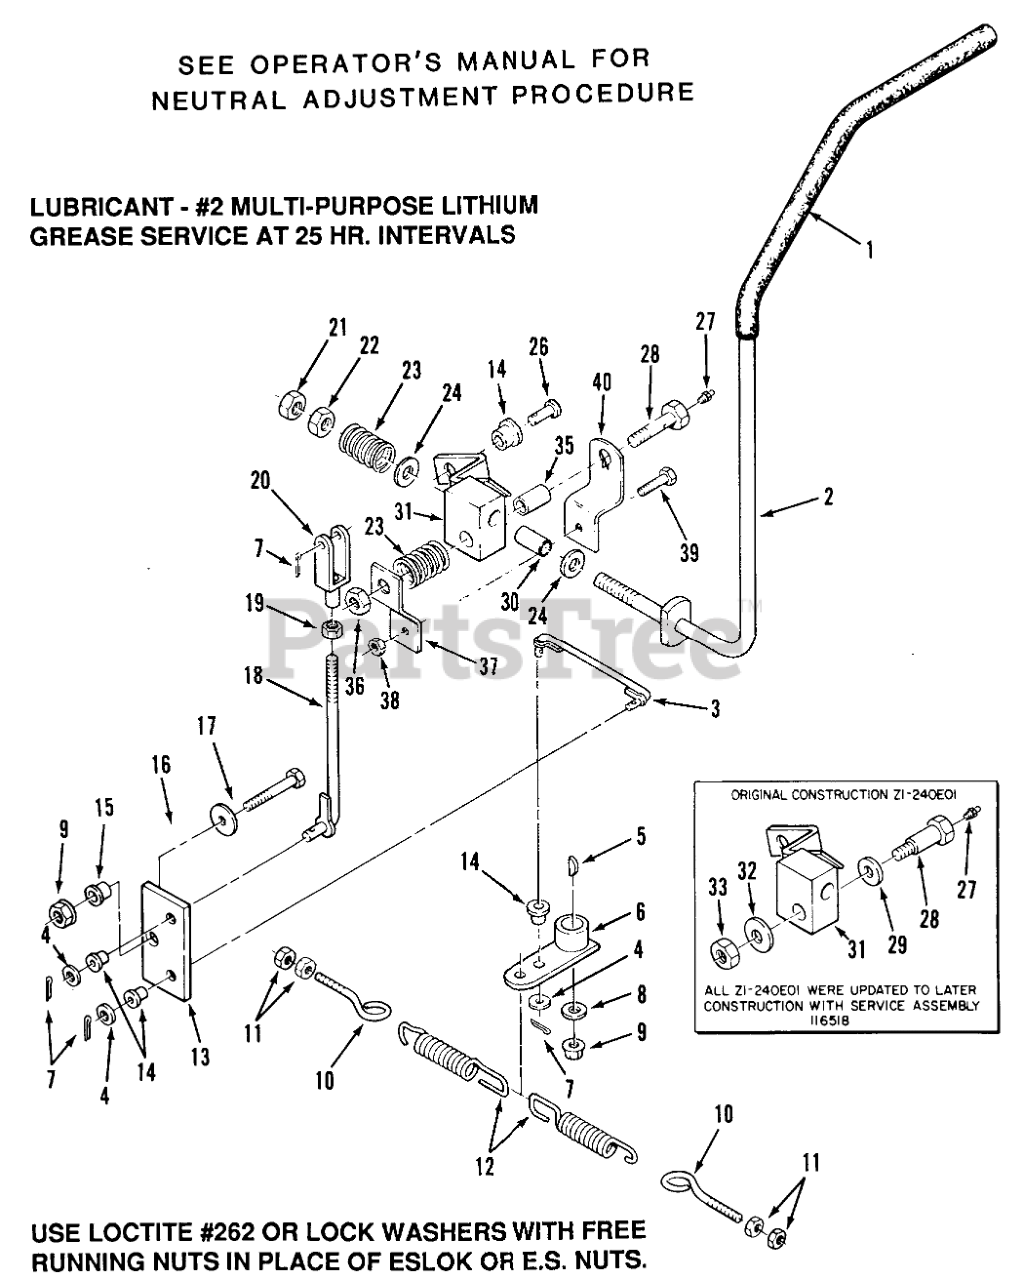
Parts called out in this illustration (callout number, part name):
1	Grip
2	ASSY-STEERING LVR LH
3	Lower Drive Linkage RH
4	WASHER 5/16 SAE
5	KEY WOODR 1/8X1/2 DI
6	Arm-Hydro Control
8	Washer
9	NUT
10	EYE BOLT 1/4-20
11	Nut
12	SPG-NEUTRAL 20217-35
13	Pivot Block
14	BUSHING-FLANGED
15	SPACER-LIFT LINK
16	WASHER
17	BOLT
18	ASS'Y-ROD
19	Nut-Lock
20	CLEVIS
21	Jam Nut
22	Eslok Nut
23	SPRING
24	Washer
26	Pin-Clevis
27	Zerk
28	Shoulder Bolt 1/2-13 x 4-1/2 (includes item 27).
29	CURVED-SPRING WASHER
30	BUSHING-STR LVR PVT
31	Steering Lever LH
32	Washer
33	NUT
34	Steering Lever LH
35	BUSHING
36	Nut
37	STRAP B
38	Nut
39	Bolt
40	Strap
41	BOLT-STEERING LEVER
